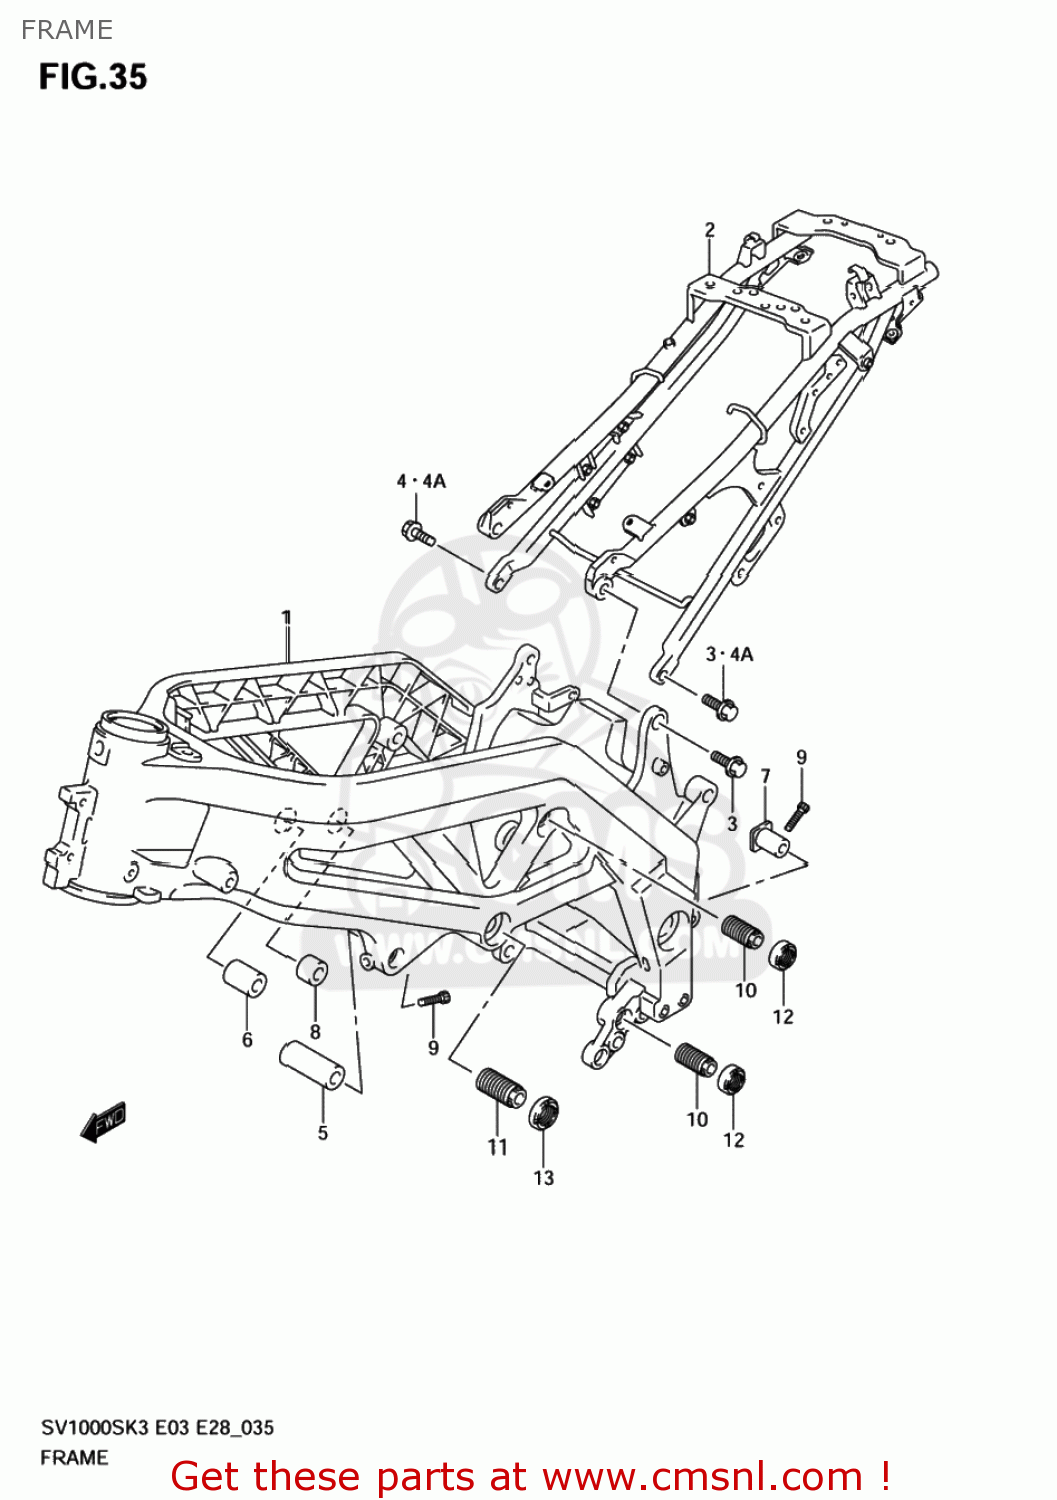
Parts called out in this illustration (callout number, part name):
1	FRAME(SILVER)
2	RAIL,SEAT
3	BOLT(10X30)
4	BOLT, SEAT LOWER RH
4A	BOLT,SEAT RAIL
5	SPACER,ENG HEAD MTG FR,L
6	SPACER,ENG HEAD MTG RR,R
7	SPACER,MOUNTING RR UPR,R
8	SPACER,ENG HEAD MTG CTR,R
9	BOLT
10	BOLT,CASE LWR & RR HEAD ADJ
11	BOLT,CRANK CASE ADJUST CTR
12	NUT,CRANK CASE ADJUST BOLT
13	NUT,CRANKCASE ADJUST
